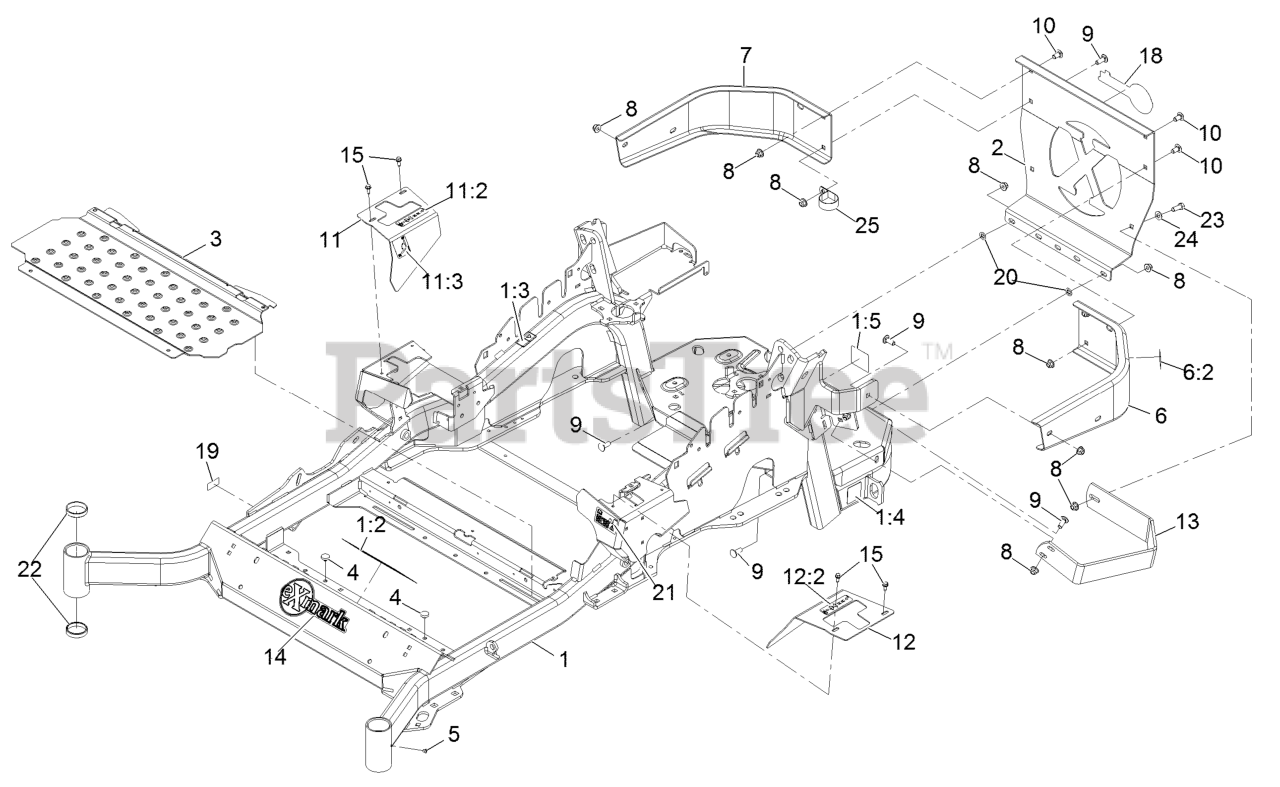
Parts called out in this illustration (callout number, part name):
1	MAINFRAME ASM
1:2	DECAL-DANGER
1:3	DECAL-WARNING
1:4	DECAL-HAZARD, PINCHED FINGER
1:5	DECAL-SPARK ARRESTER
2	PLATE,REAR GUARD
6	LH BUMPER ASM
6:2	DECAL-WARNING
7	BUMPER-RH
8	NUT-HF, NI
9	SCREW-CARR
10	SCREW-CARR
11	RH MOTION CONTROL COVER ASM
11:2	DECAL-CONTROL, MOTION
11:3	DECAL-PARK BRAKE, CE
12	LH MOTION CONTROL COVER ASM
12:2	DECAL-CONTROL, MOTION
13	GUARD-MUFFLER
14	DECAL-EXMARK LOGO
15	SCREW-HWH
18	DECAL-EXMARK LOGO
19	Decal-Patent
20	NUT-PUSH
21	DECAL-FUEL FILL, CE
22	CUP-BEARING
23	SCREW-HH
24	WASHER-FLAT
25	CLAMP-R
